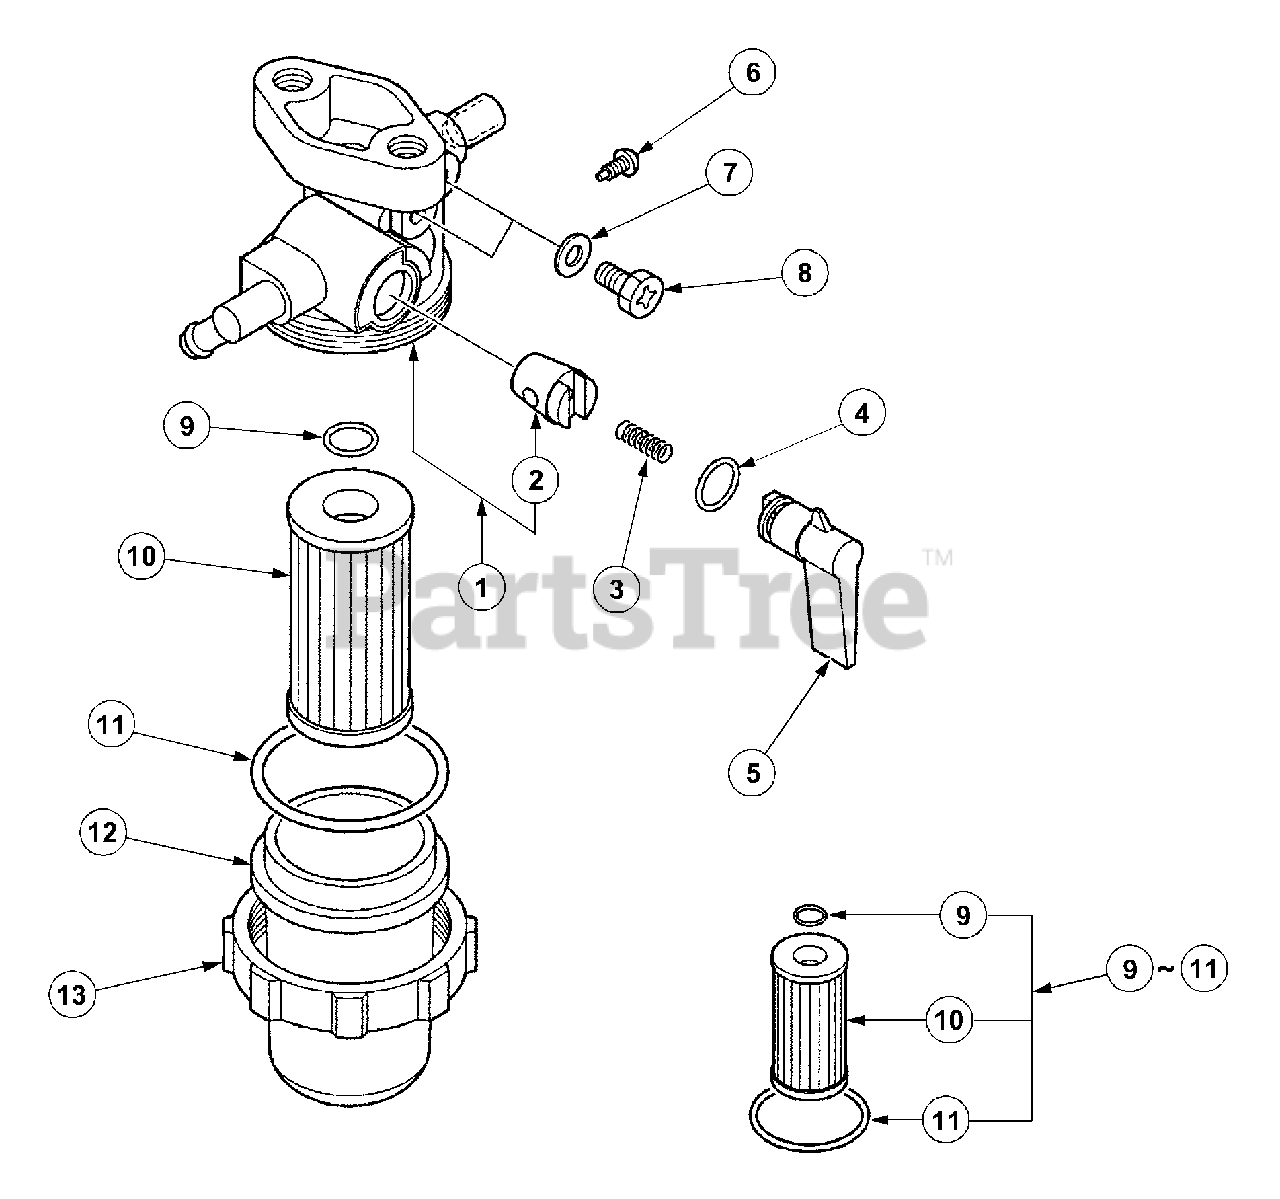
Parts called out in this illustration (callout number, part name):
1	Body Sub Assy
2	Valve
3	Spring,Valve
4	O-Ring
9	O-Ring
10	Element
11	O-Ring
